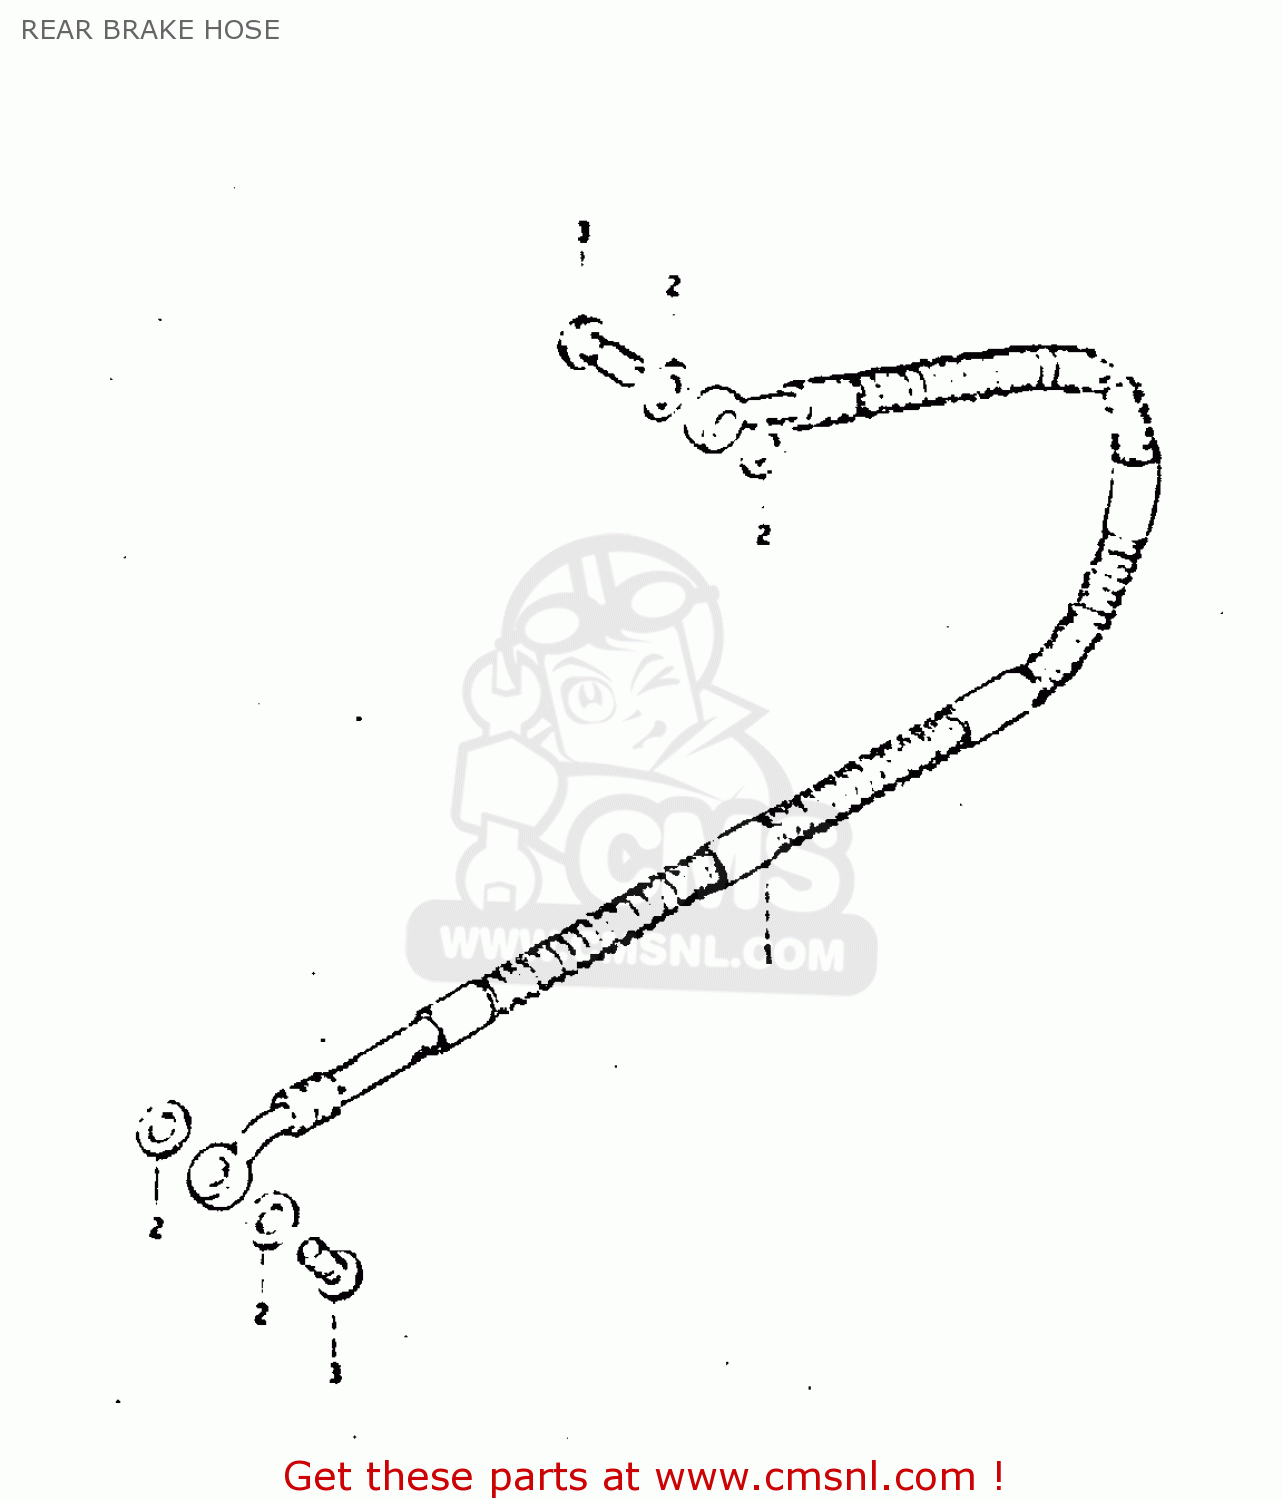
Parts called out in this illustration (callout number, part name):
1	HOSE,REAR BRAKE
2	WASHER
3	BOLT,UNION
